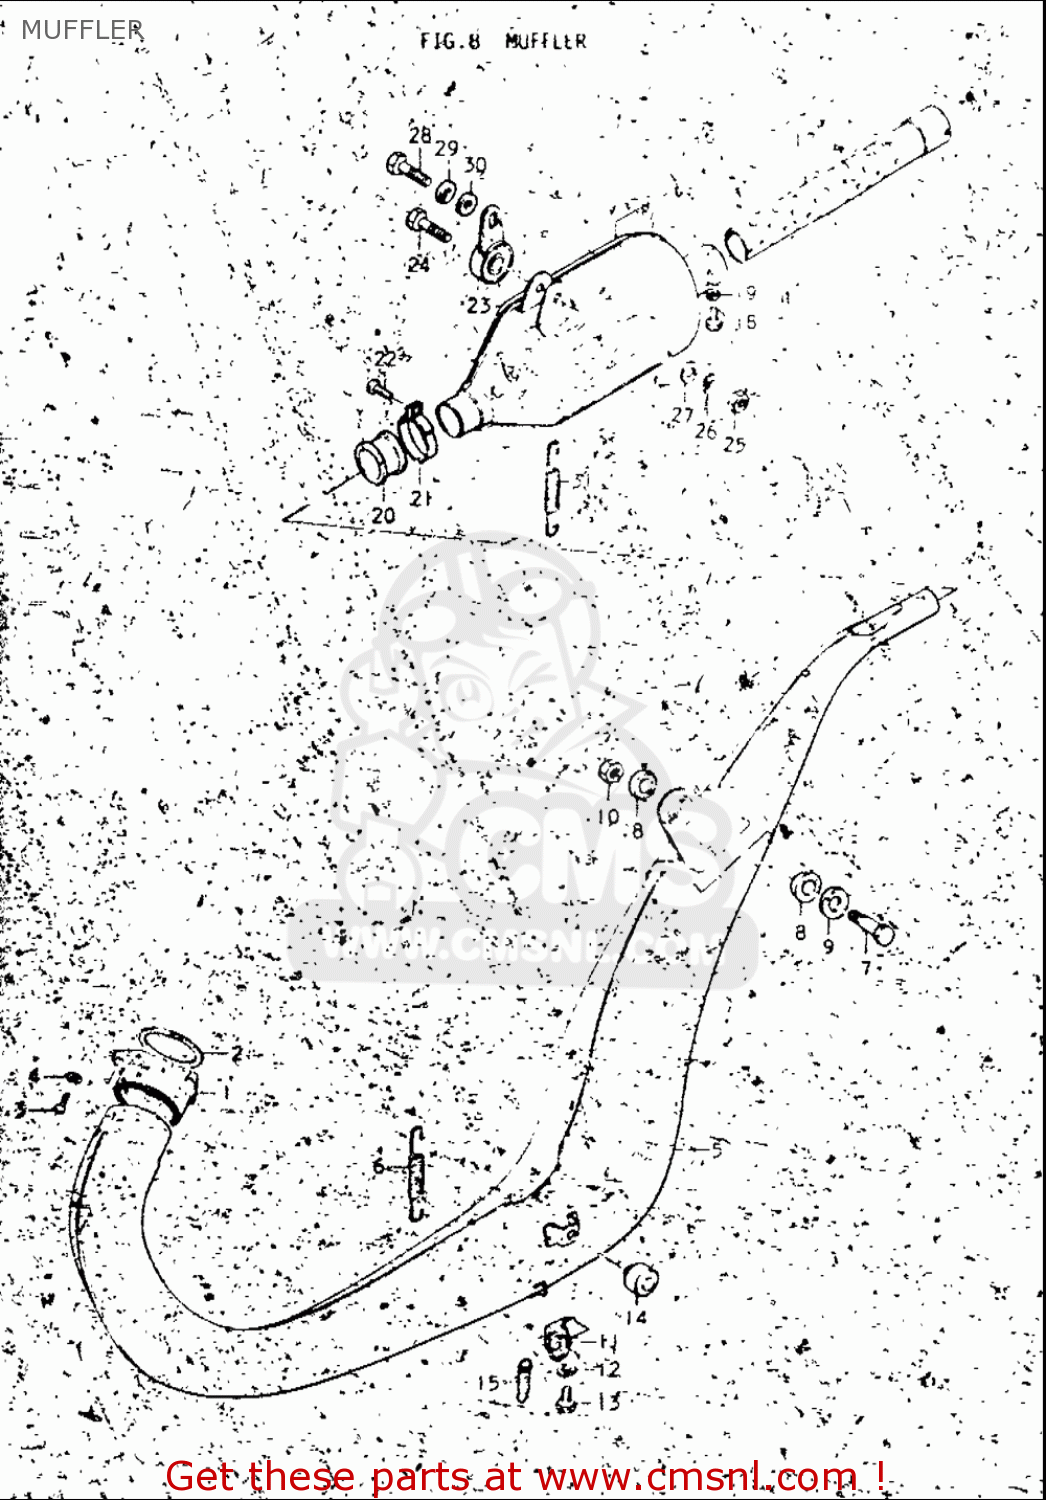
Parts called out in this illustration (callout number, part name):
2	GASKET,EXHAUST PIPE (NAS)
3	SCREW
4	WASHER,LOCK
6	SPRING
7	BOLT
9	WASHER (8.2X22X3.2)
10	NUT
11	BRACKET, MUFFLER STOPPER
12	WASHER,LOCK
13	BOLT
14	CUSHION(11.5X22X20)
15	SPRING
18	SCREW(6X8)
19	WASHER,LOCK
22	SCREW
24	BOLT
25	NUT
26	WASHER,LOCK
27	WASHER
28	BOLT
29	WASHER,LOCK
30	WASHER
31	SPRING
